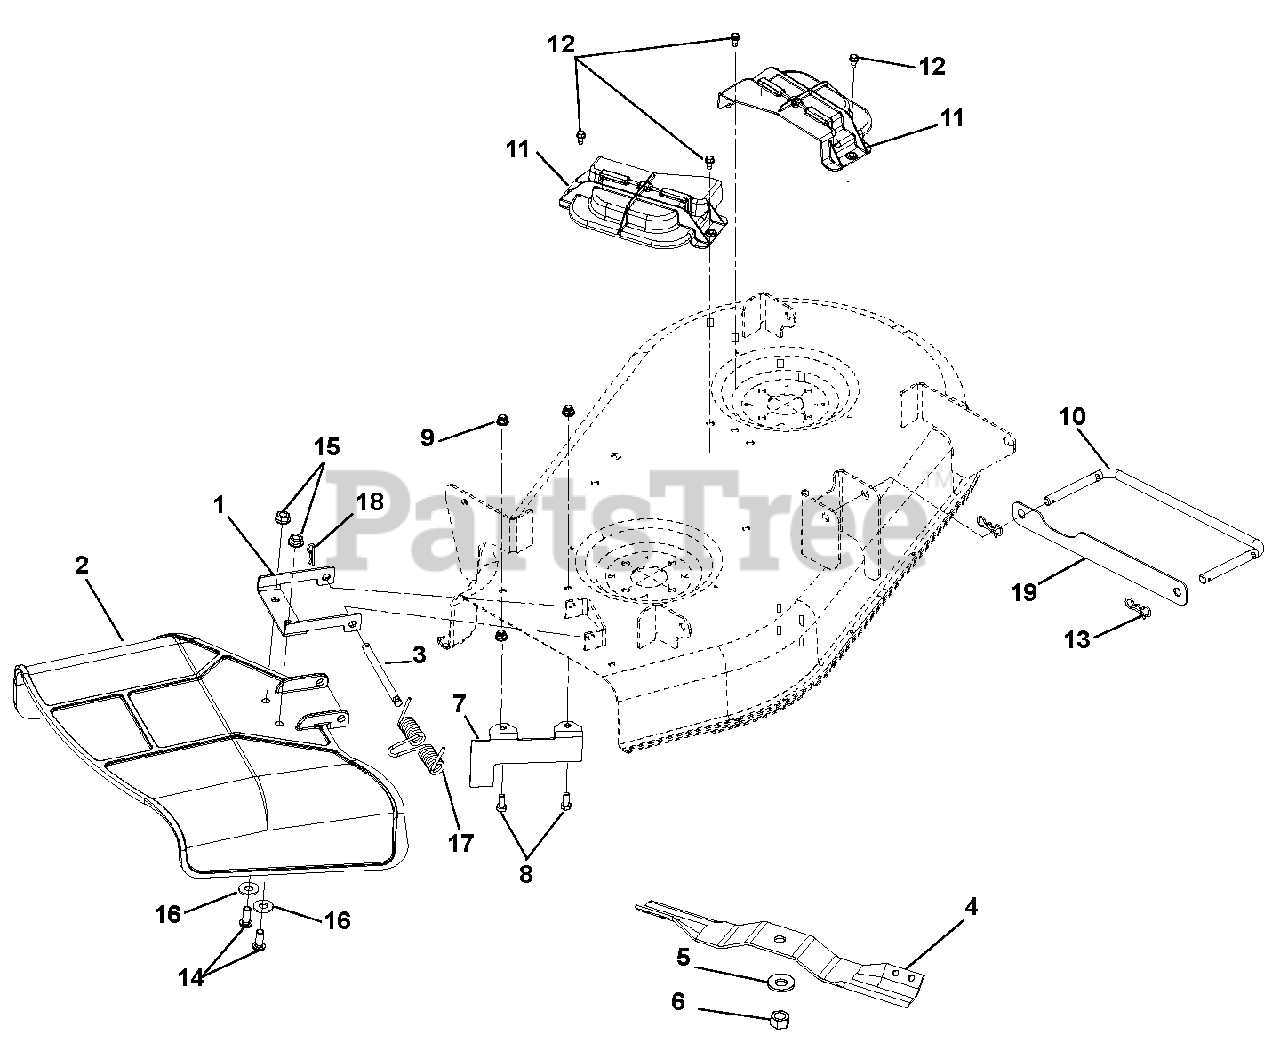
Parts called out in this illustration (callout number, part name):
1	Chute Reinforcement
2	Molded Chute
3	Pin, 5/16 x 3.88"
4	Blade, Mower 17.35
5	Washer, Beveled .63 x 1.625 x .14
6	Nut, Hex .62-18
7	Bracket, Baffle Discharge 34"
8	Bolt, Hex .31-18 x .75
9	Nut, .31-18 Nyloc Flange
10	Wireform, Drag Link
11	Molded Cover, Belt
12	Screw, Tapping .25-20 x .50 Hex Washer Head
13	Pin, Bow Tie Locking Cotter .091 x 1.875
14	Screw, .31-18 x .75
15	Nut, Locking Top Flange .31-18
16	Washer, Flat Steel .38 x .875 x .083
17	Spring, Torsion
18	Pin, Hair .08 x .18 x 1.18
19	Strap, Drag Link
